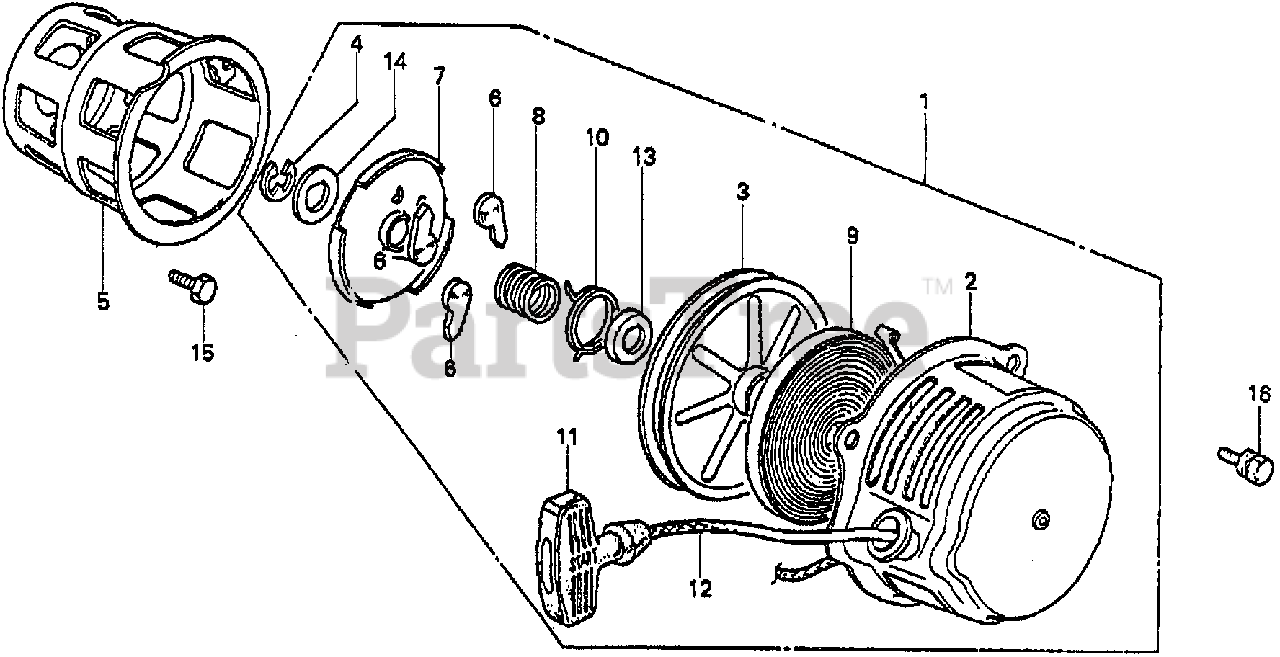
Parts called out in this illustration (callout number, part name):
1	STARTER ASSY., RECOIL *R8* (BRIGHT RED) (NOT AVAILABLE)
2	CASE, RECOIL STARTER *R8* (BRIGHT RED)
3	PULLEY, RECOIL STARTER
5	PULLEY, STARTER
6	RATCHET, STARTER
7	PLATE, FRICTION
8	SPRING, FRICTION
9	SPRING, STARTER RETURN
10	SPRING SET
11	KNOB SET, STARTER
12	ROPE, STARTER (#6X64")
15	BOLT, HEX. (6X12)
16	BOLT-WASHER (6X12)
